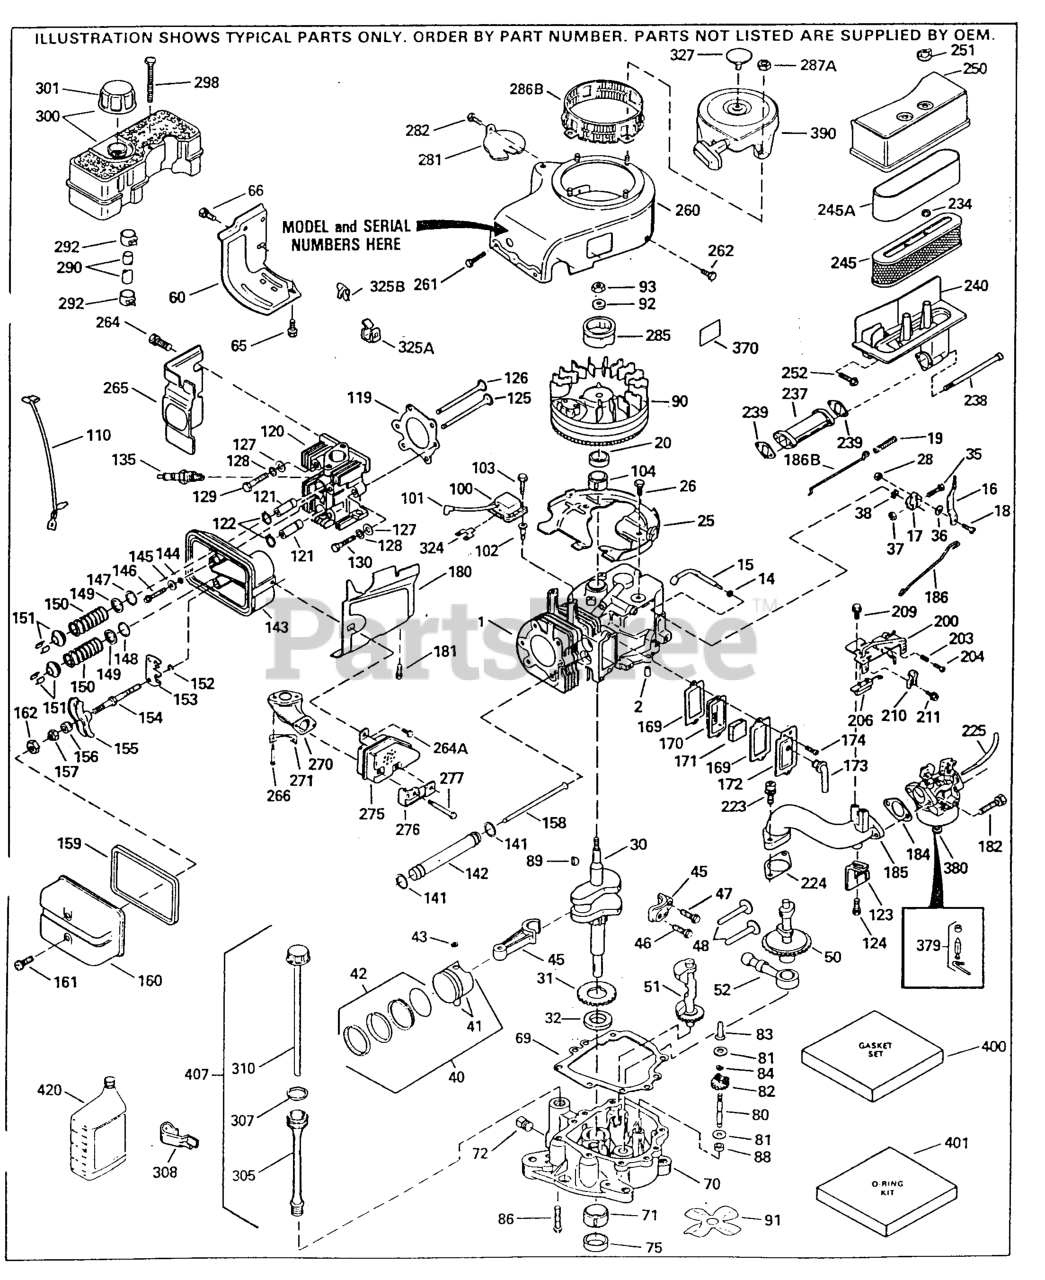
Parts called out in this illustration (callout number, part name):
1	CYLINDER
15	GOVERNOR ROD
16	GOV LEVER
18	SCREW
19	EXT SPRING
20	OIL SEAL
25	BAFFLE
30	CRANKSHAFT
38	RET RING
40	PISTON ASSY 020
40	PISTON ASSY STD
40	PISTON ASSY 010
41	PISTON ASSY 020
41	PISTON ASSY 010
41	PISTON ASSY STD
42	RING SET STD
42	RING SET 020
42	RING SET 010
43	RET RING
45	CONN ROD
46	SCREW
47	SCREW
48	VALVE LIFTER
50	CAMSHAFT
52	OIL PUMP
60	EXTENSION
70	MTG FLANGE
72	PIPE PLUG
75	OIL SEAL
80	GOV SHAFT
81	WASHER
83	GOV SPOOL
84	RET RING
90	FLYWHEEL
91	CRANKSHAFT FAN
100	LAMINATION
101	PLUG COVER
102	STUD
103	SCREW
110	GROUND WIRE
120	CYL HEAD
121	VALVE GUIDE
122	Ring, Retaining
125	EXH VALVE STD
125	EXH VALVE OS
126	INT VALVE ST
126	INT VALVE OS
128	WASHER KIT
130	SCREW--NLA
135	SPARK PLUG
142	ROD TUBE
143	ROCKER HSG
149	VALVE CAP
150	VALVE SPRING
151	VALVE RET
155	ROCKER ARM KIT
156	BEARING
158	PUSH ROD
160	COVER
170	BREATHER
171	ELEMENT
172	VALVE COVER
180	EXTENSION
185	INTAKE PIPE
186	GOV LINK
200	CONTROL ASSY
203	COMP SPRING
204	SCREW
223	Screw, 5/16-18 x 7/8"
237	ADAPTER-NLA
240	CLEANER BODY
245	AIR CLEANER
245A	AIR CLEANER
250	CLEANER COV
260	BLOWER HSG
290	FUEL LINE
305	FILLER TUBE
310	DIPSTICK
370	DECAL
380	CARBURETOR
400	GASKET SET
401	O RING KIT
420	OIL SAE 30
